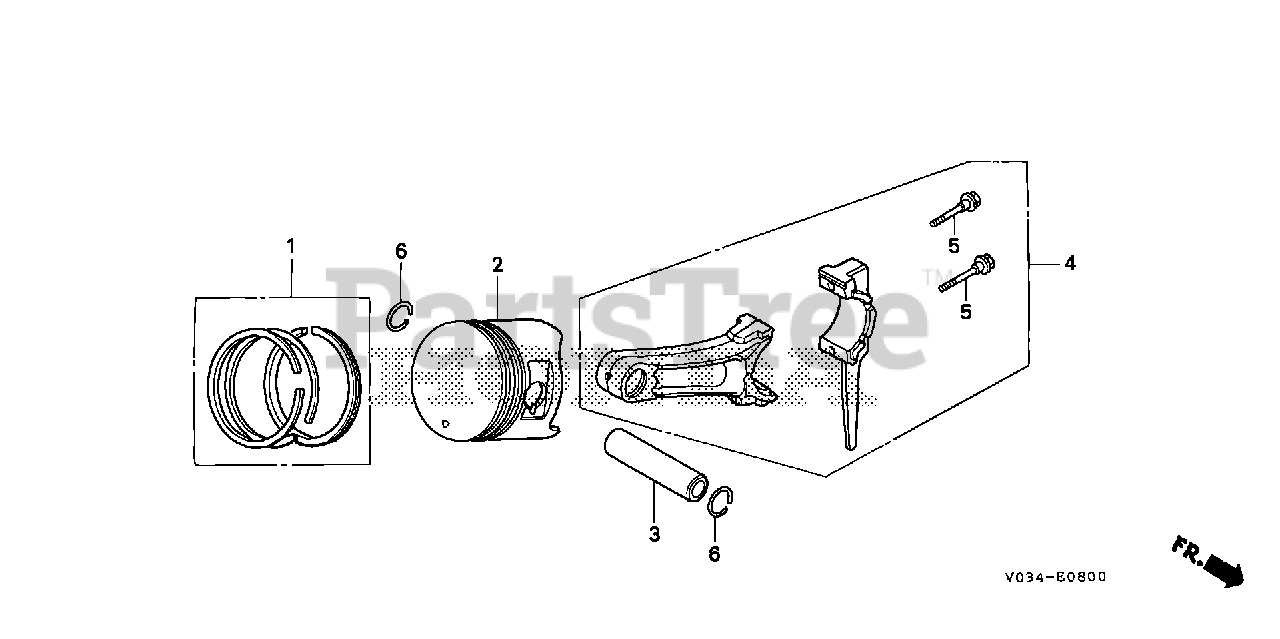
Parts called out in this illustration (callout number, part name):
1	RING SET, PISTON (STD) (NIPPON)
1	RING SET, PISTON (STD) (TPR)
1	RING SET, PISTON (0.25) (NIPPON)
1	RING SET, PISTON (0.25) (TPR)
1	RING SET, PISTON (0.50) (NIPPON)
1	RING SET, PISTON (0.50) (TPR)
1	RING SET, PISTON (0.75) (NIPPON)
1	RING SET, PISTON (0.75) (TPR)
2	PISTON (STD)
2	PISTON (0.25)
2	PISTON (0.50)
2	PISTON (0.75)
3	PIN, PISTON
4	ROD ASSY., CONNECTING (STD)
5	BOLT, CONNECTING ROD
6	CLIP, PISTON PIN (20MM)
